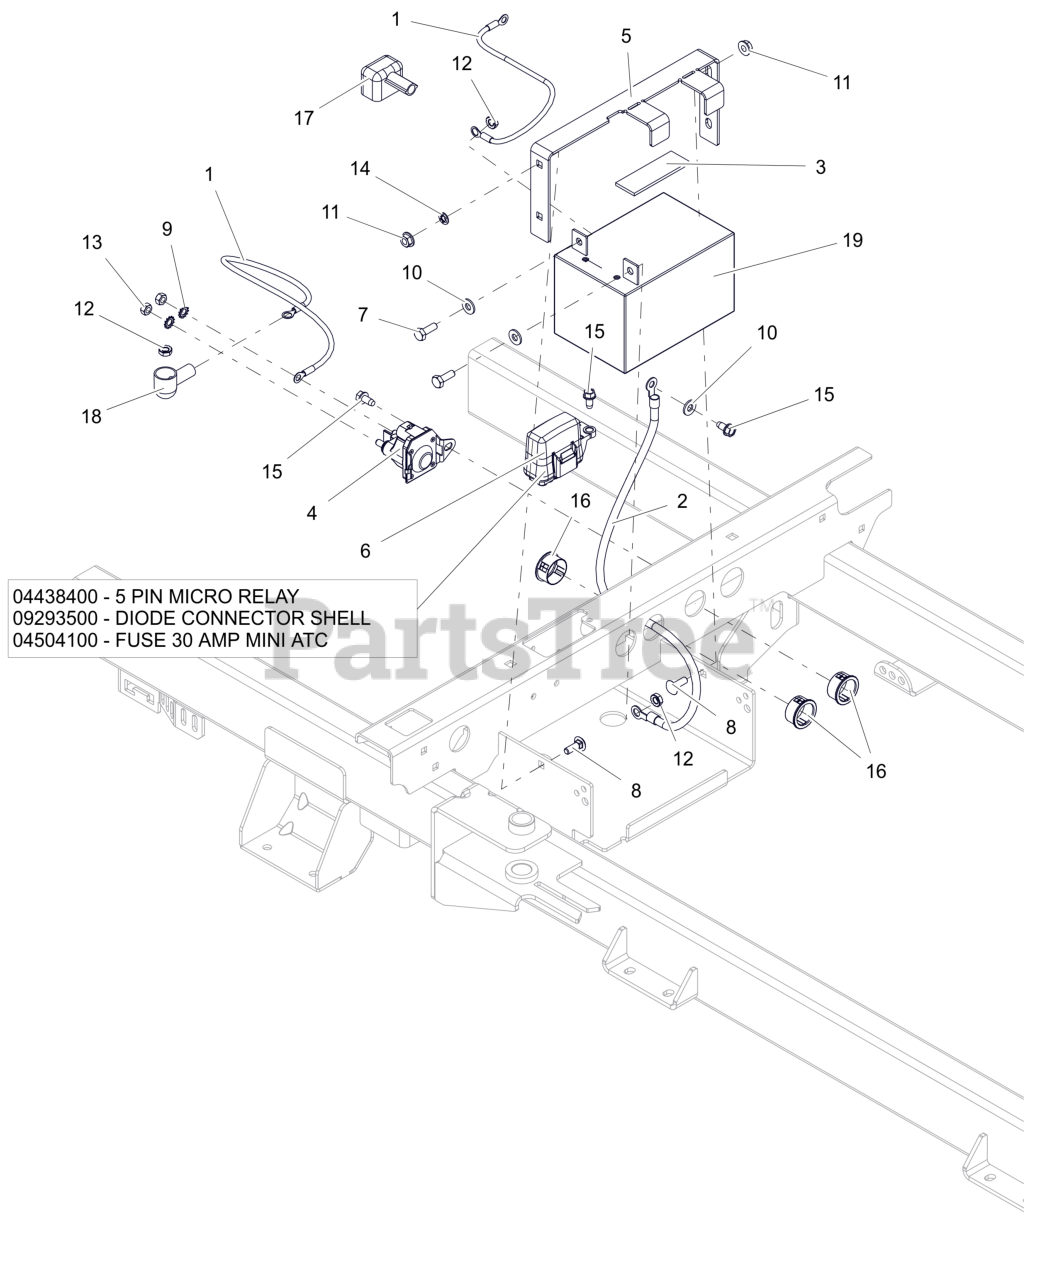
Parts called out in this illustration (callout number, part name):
1	CABLE,POS W/2 1/4 RING 15.0 LG
1	RELAY,MICRO5 TERML W/RESISTOR
1	DIODE, CONNECTOR SHELL
1	FUSE,30 AMP MINI-ATC
2	CABLE-NEGATIVE BATTERY 24.00"
3	PAD,RBR 1.0"X3.0" W/ADHESIVE
4	SOLENOID, STARTER (SEALED)
5	BRKT, BATTERY HOLD-DOWN (BLACK)
6	HARNESS, WIRE
7	BLT, HEX .25-20X.75 G5 ZCC
8	BLT, RHSN .25-20X.750 G5 ZCC
9	WSHR,LK-EXT.262X.502X.026 ZCC
10	WSHR,FLT .281X.625X.065 ZCC
11	NUT-LK-TOP-FLG .250-20 GF ZCC
12	NUT-KEPS .250-20 ZCC
13	NUT-STD M6-1.0 ZCC
14	NUT-PUSH .25X.50 O.D.
15	SCR-TAP .25-20X.50 HWH ZCC
16	BSHG, PANEL SNAP .937X1.11X.56
17	INSULATOR
18	BOOT, EYELET TERMINAL
19	BATTERY, 12V 12A -190CCA
